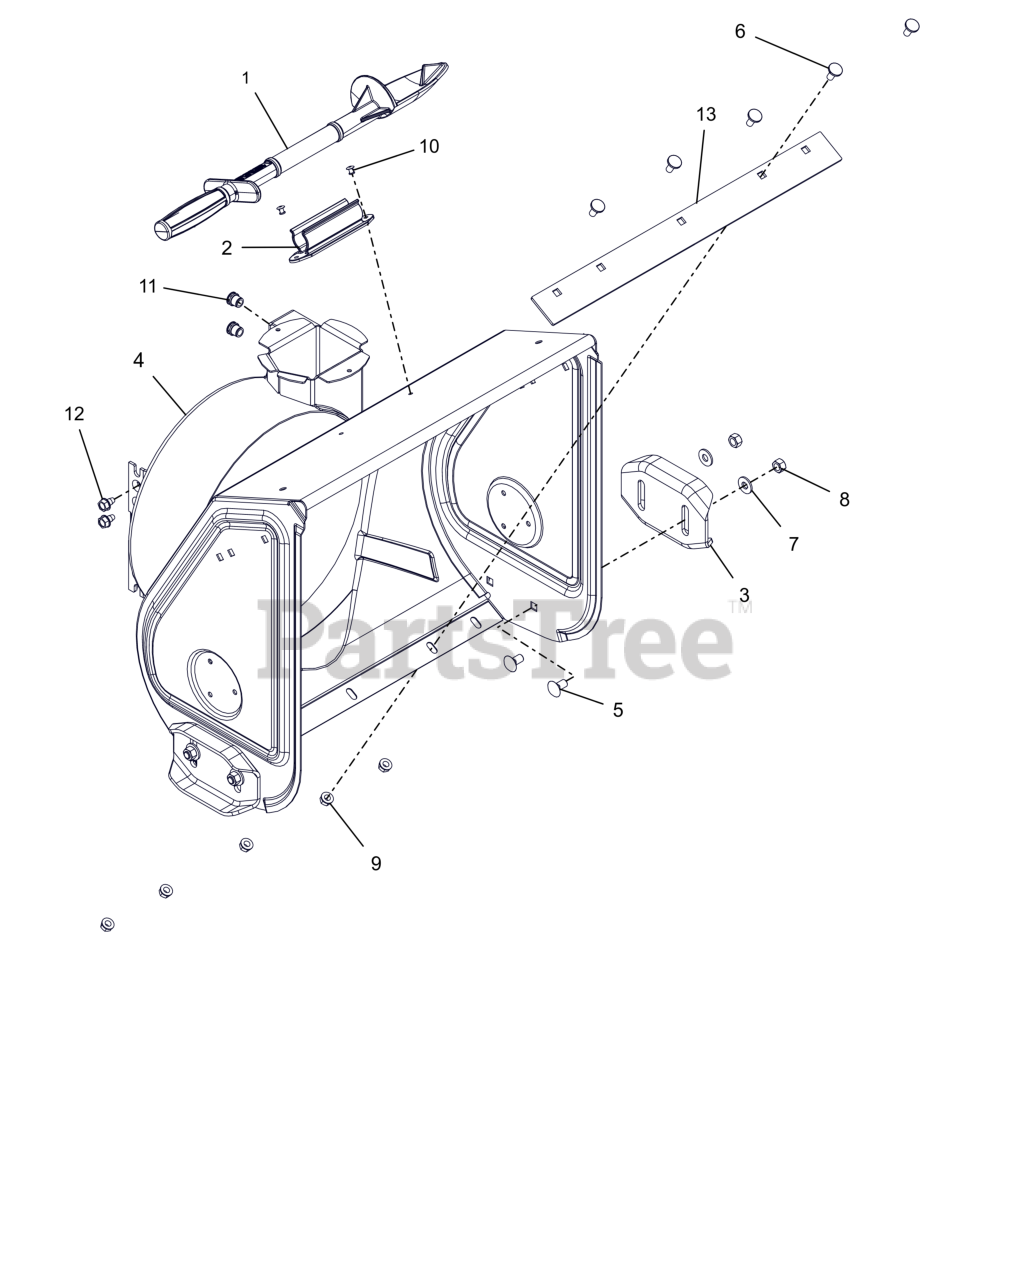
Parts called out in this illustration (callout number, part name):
1	DEVICE, SNOW CLEAN OUT
2	MOUNT, SNOW CLEAN OUT
3	SKID SHOE, REVERSIBLE - ORANGE
4	BLOWER HOUSING, 20" HB SERVICE
5	BLT, RHSSN .38-16X.75 G5 ZCC
6	BOLT, MODIFIED HEAD CARRIAGE
7	WSHR,FLT .375X.875X.083 ZCC
8	NUT-LK-CTR .38-16 ZC120
9	NUT-LK-TOP-FLG .312-18 GF ZCC
10	RVT, POP .1875 ZCC
11	NUT,THD,INSERT .38-16 ZC120
12	SCR,TAP .312-18X.50 HWH TR ZCC
13	SCRAPER BLADE, 20"
